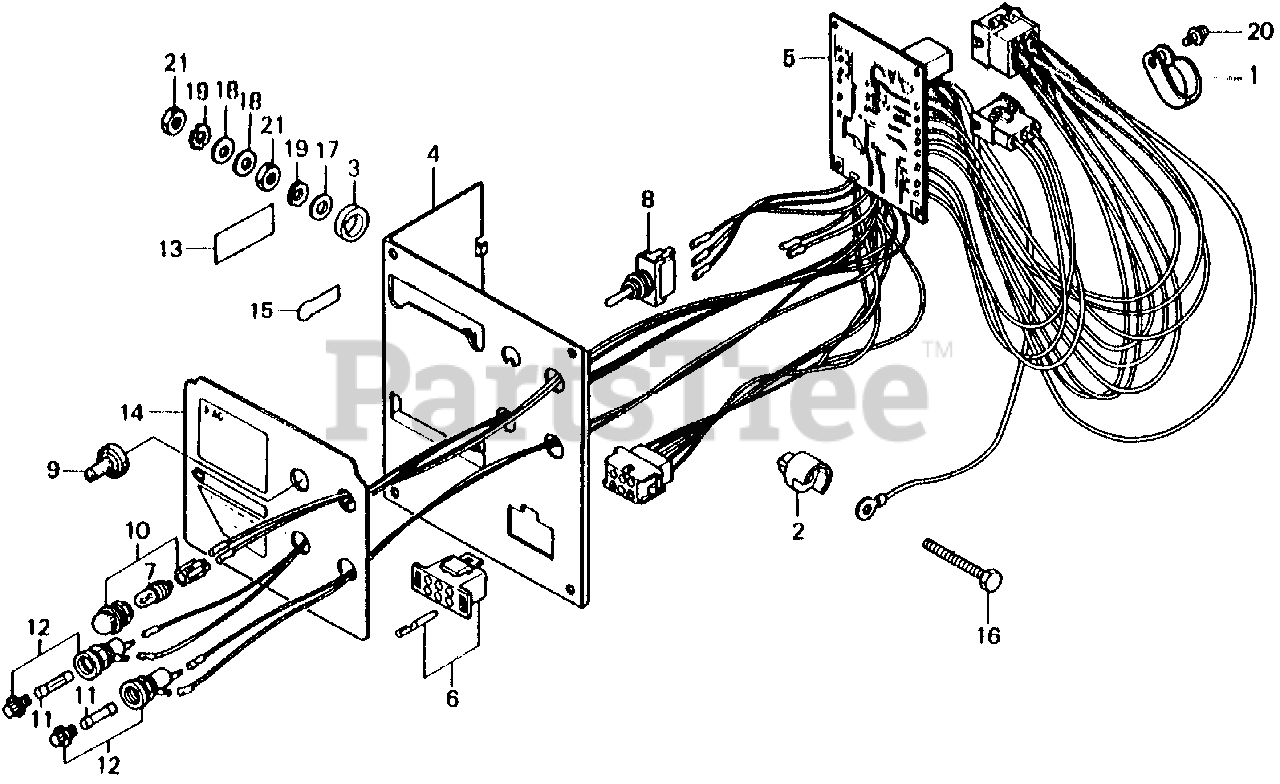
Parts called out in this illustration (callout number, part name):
1	CLAMP C, CABLE
2	COLLAR A, D.C. TERMINAL
3	COLLAR B, D.C. TERMINAL
4	PANEL, CONTROL BOX *NH116M* (URBAN SILVER METALLIC) (NOT AVAILABLE)
5	CIRCUIT ASSY., PRINT (NOT AVAILABLE)
6	CONNECTOR ASSY., PLUG
7	BULB (12V2W)
8	SWITCH ASSY., ENGINE (NOT AVAILABLE)
9	CAP, SWITCH
10	HOLDER, LAMP
12	HOLDER, FUSE
13	MARK, WIRE CAUTION
14	PLATE, CONTROL PANEL (LOWER)
15	MARK, BATTERY
16	BOLT, B.C. TERMINAL
17	WASHER, EQUALIZER (8MM) (NOT AVAILABLE)
18	WASHER, D.C. TERMINAL
19	WASHER, STAR
20	SCREW-WASHER (4X10)
21	NUT, HEX. (8MM)
